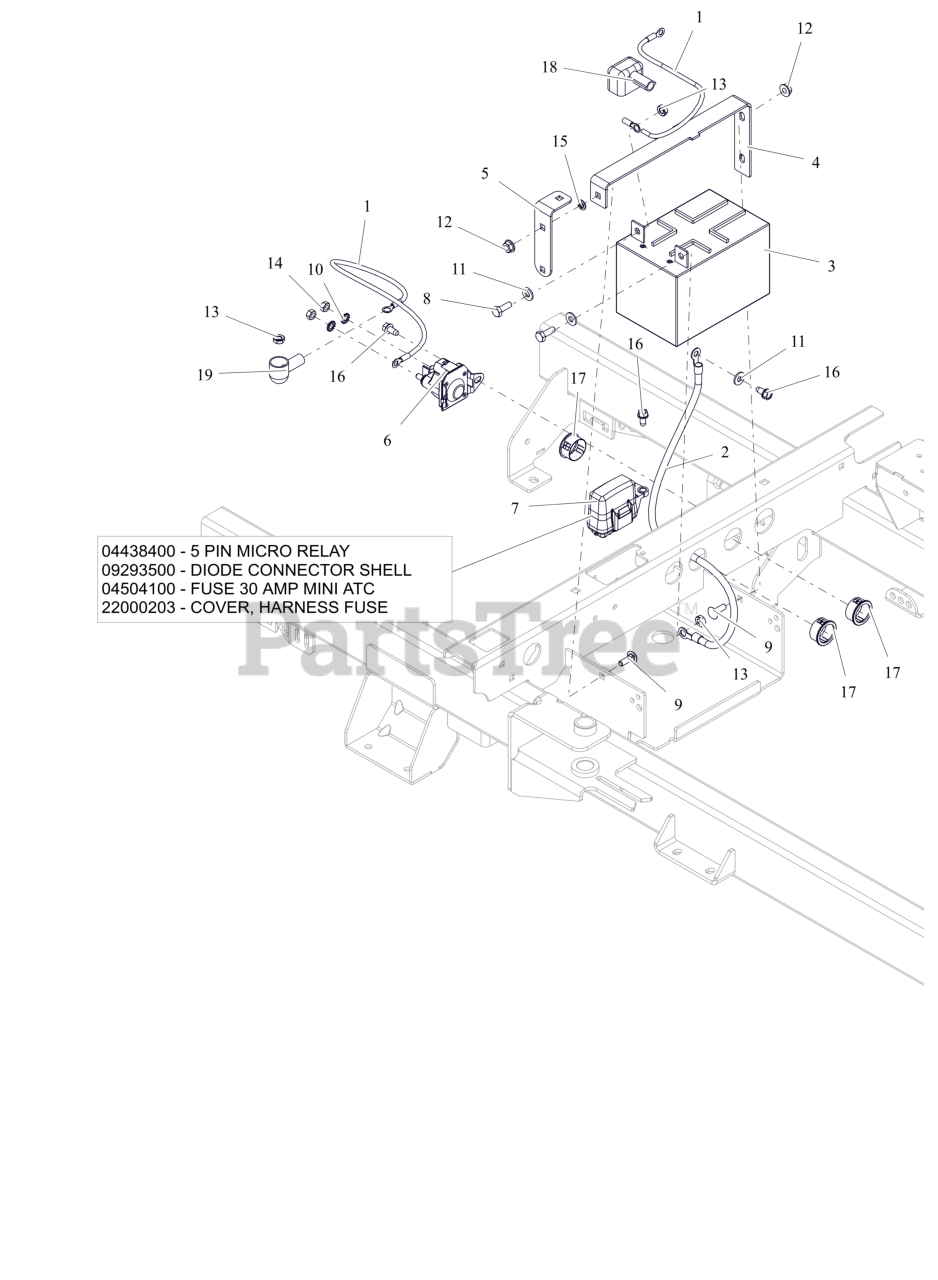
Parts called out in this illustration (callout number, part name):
1	CABLE,POS W/2 1/4 RING 15.0 LG
2	CABLE-NEGATIVE BATTERY 24.00"
3	BATTERY, 12V 12A-190CCA
4	BRKT, BATTERY HOLD-DOWN
5	BRKT, BATTERY HOLD DOWN
6	SOLENOID, STARTER (SEALED)
7	HARNESS, WIRE
7	RELAY,MICRO5 TERML W/RESISTOR
7	DIODE, CONNECTOR SHELL
7	FUSE,30 AMP MINI-ATC
7	COVER, FUSE
8	BLT, HEX .25-20X.75 G5 ZCC
9	BLT, RHSN .25-20X.750 G5 ZCC
10	WSHR,LK-EXT.262X.502X.026 ZCC
11	WSHR,FLT .281X.625X.065 ZCC
12	NUT-LK-TOP-FLG .250-20 GF ZCC
13	NUT-KEPS .250-20 ZCC
14	NUT-STD M6-1.0 ZCC
15	NUT-PUSH .25X.50 O.D.
16	SCR-TAP .25-20X.50 HWH ZCC
17	BSHG, PANEL SNAP .937X1.11X.56
18	INSULATOR
19	BOOT, EYELET TERMINAL
